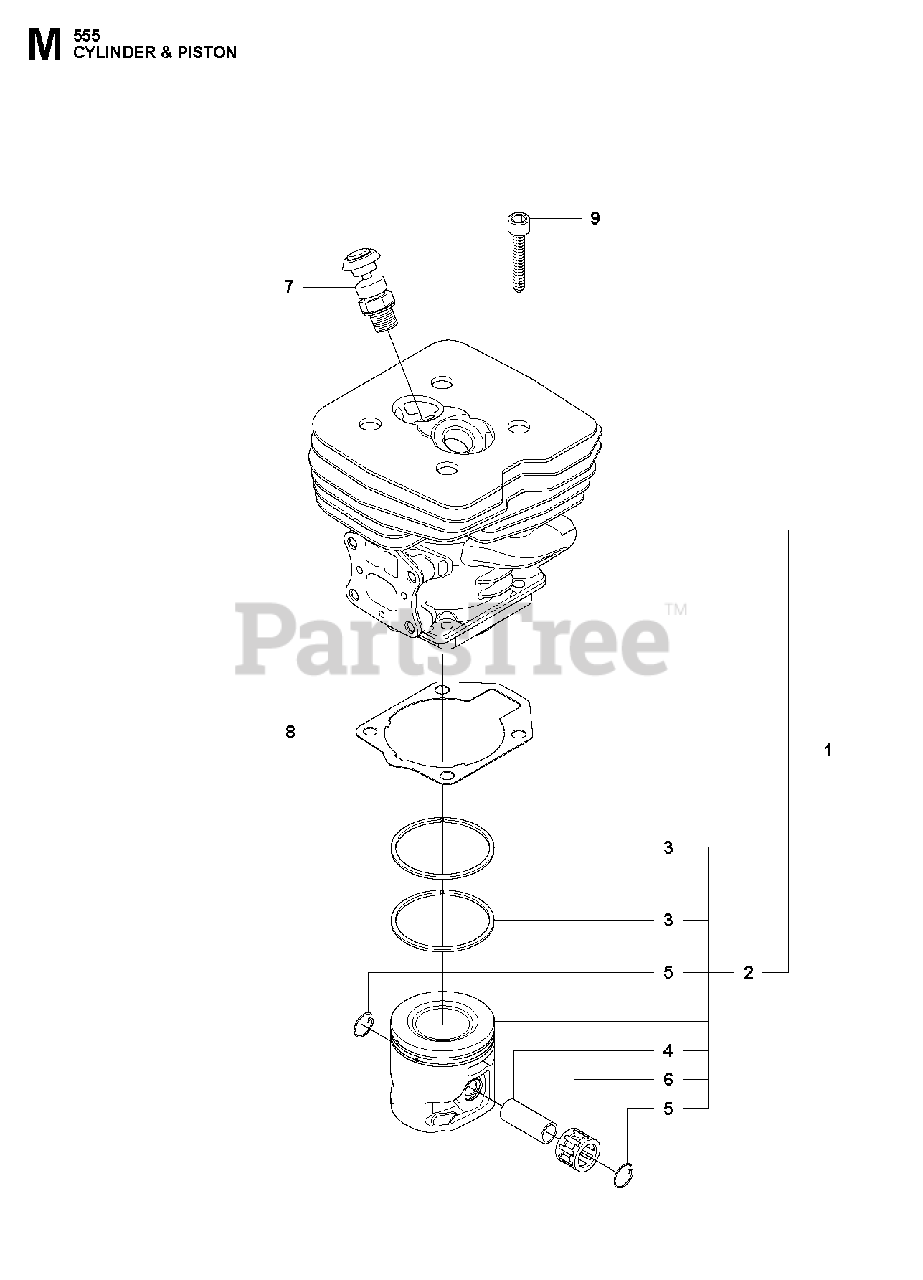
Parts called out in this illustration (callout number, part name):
1	CYLINDER ASSY
2	PISTON ASSY
3	PISTON RING
4	PISTON PIN
5	CIRCLIP B10X0.8
6	SUPPORT BUSHING
7	DECOMPRESSION VALVE
9	SCREW MC6S 5X25
